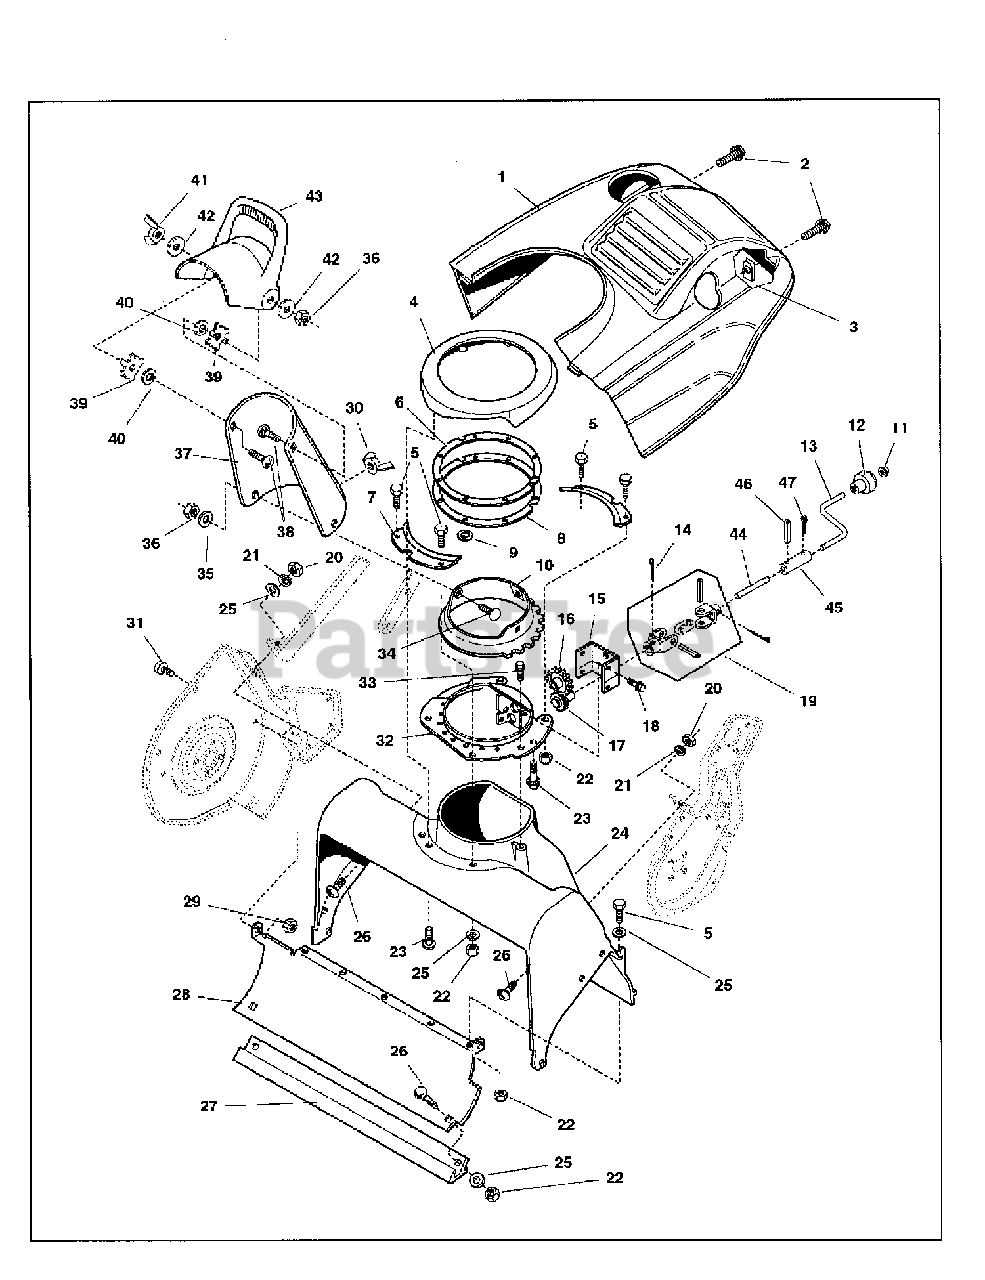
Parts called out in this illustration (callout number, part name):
1	HOUSING, Upper Plastic w/Louvers 520 Snow
2	SCREW, Hex Head, Taptite #10-24 x 1"
3	NUT, Retainer, Speed #10-24 w/Extrusion
4	COLLAR
5	CAPSCREW, Hex Head, 1/4-20 x 3/4" GR 5
6	GASKET
7	RETAINER
8	RETAINER, Gasket
9	NUT, Push
10	BASE, Chute
11	NUT, Push, Pal, 3/8"
12	KNOB, Chute, Rotate
13	HANDLE, Chute Rotator Upper
14	PIN, Cotter, 1/8 x 1-1/2"
15	BRACKET, Gear
16	GEAR, Idler
17	GEAR, Drive
18	SCREW, Hex Head Taptite, 1/4-20 x 5/8"
19	ASSEMBLY, Universal Joint
20	NUT, Hex, 1/4-20
21	LOCKWASHER, Spring, 1/4"
22	NUT, Hex Lock Esna 1/4-20
23	SCREW, Hex Washer Slotted Head Plastite #10-14 x 5/8"
24	HOUSING, Auger
25	WASHER, 1/4"
26	CARRIAGE BOLT, 1/4-20 x 7/8", GR 5
27	SCRAPER BAR
28	SCOOP
29	NUT, Hex Lock, #10-24
30	NUT, Wing 5/16-18 Lock
31	SCREW, Truss Head Torx, #10-24 x 5/8" GR 5
32	PLATE, Chute Base
33	SCREW, Hex Washer Slotted Head Plastite #10-14 x 5/8"
34	CARRIAGE BOLT, 5/16-18 x 3/4"
35	WASHER, 5/16
36	NUT, Hex Lock ESNA Light, 5/16-18
37	CHUTE
38	BOLT, Carriage, Short Neck, 5/16-18 x 1
39	WASHER, Octagon
40	WASHER, Rubber
41	KNOB, Wing (5/16-18 Black)
42	WASHER, 1-1/2 O.D.
43	DEFLECTOR, Chute
44	HANDLE, Chute Rotator Lower, E-Coat
45	TUBE, Chute Handles 1/2 OD 7.00 Long E-Coat
46	PIN, Spring 5/32 x 1" SAE 1095
47	CLIP, Hair Pin .093 Dia. Spring Wire 1.625 long
